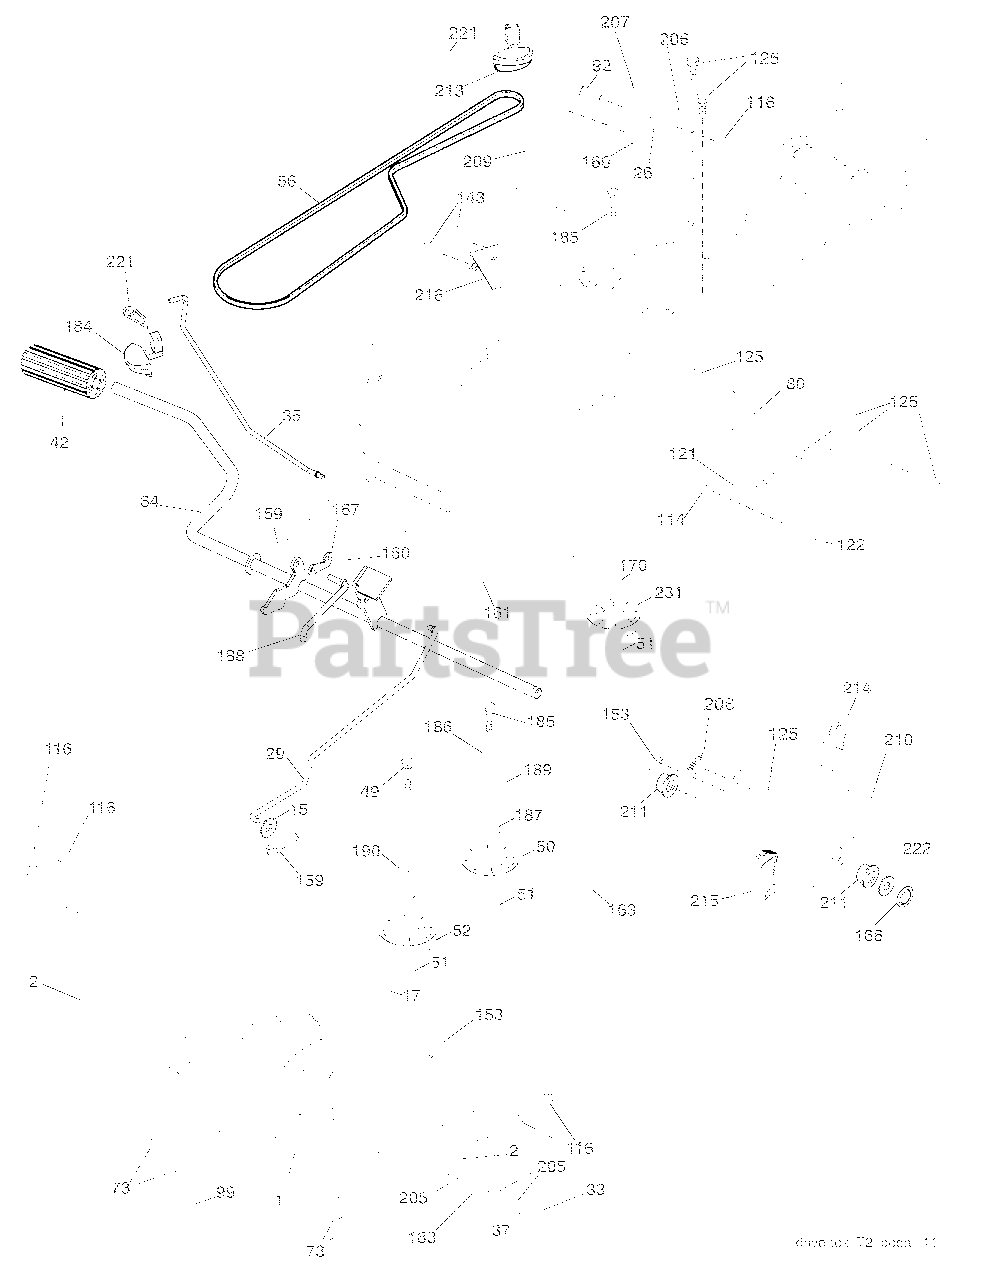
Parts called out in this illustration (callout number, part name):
1	Transaxle, Hydro Gear T2 (Internal Parts Not Available)
2	Key Square
15	Washer 13/32 x 13/16 x 16 Ga.
17	Spring, Brake
26	Spring Return Cruise
29	Rod, Brake
35	Rod, Brake, Park
37	Washer 25/32 x 1-1/4 x 16 Ga.
42	Cover, Foot Pedal
50	Pulley Idler Flat
51	Lock Nut 3/8-16
52	Idler V-Groove 910" Offset
56	V-Belt, Drive
64	Shaft Asm. Pedal Brake Control
73	Bolt Hex 5/16-18 Gr. 5
80	Strap Torque
92	Bolt Fin Hex 5/16-18 unc x 1.25
99	Rod Spring Bypass
114	Nut Lock HX w/Ins 5/16-18
116	Nut Lock Hex Flange 5/16-18
121	Bracket Strap Torque
122	Bolt 5/16-18 x 2.50
125	Screw 5/16-18 x 3/4
143	Screw 5/16-18 x 1/2
153	Retainer Spring 1"
159	Pin Cotter 1/8 x 3/4
160	Retainer Clip
161	Spring, Return, Clutch
163	Rod Control
166	Nut Push
167	Latch Brake Parking
170	Keeper V-Idler
183	Spacer Axle
184	Handle Parking Brake
185	Bolt
186	Spacer Retainer
187	Washer
188	Link Clutch Ground Drive
189	Bellcrank Ground Drive
190	Keeper Bellcrank Ground Drive
205	Washer 25/32 x 1-5/8 x 16 Ga.
206	Bracket Mount Latch Cruise
207	Latch Control Cruise
208	Gear Sector Control Cruise
209	Rod Control Cruise
210	Rocker Asm. Pedal Control
211	Bearing Nylon
213	Knob Control Cruise
214	Pedal Forward
215	Pedal Reverse
216	Bracket Pulley Idler
221	Retainer Spring Clip Handle
222	Washer 21/32 x 1-1/4 10 Ga.
231	Idler V-Groove 1.688" Offset
